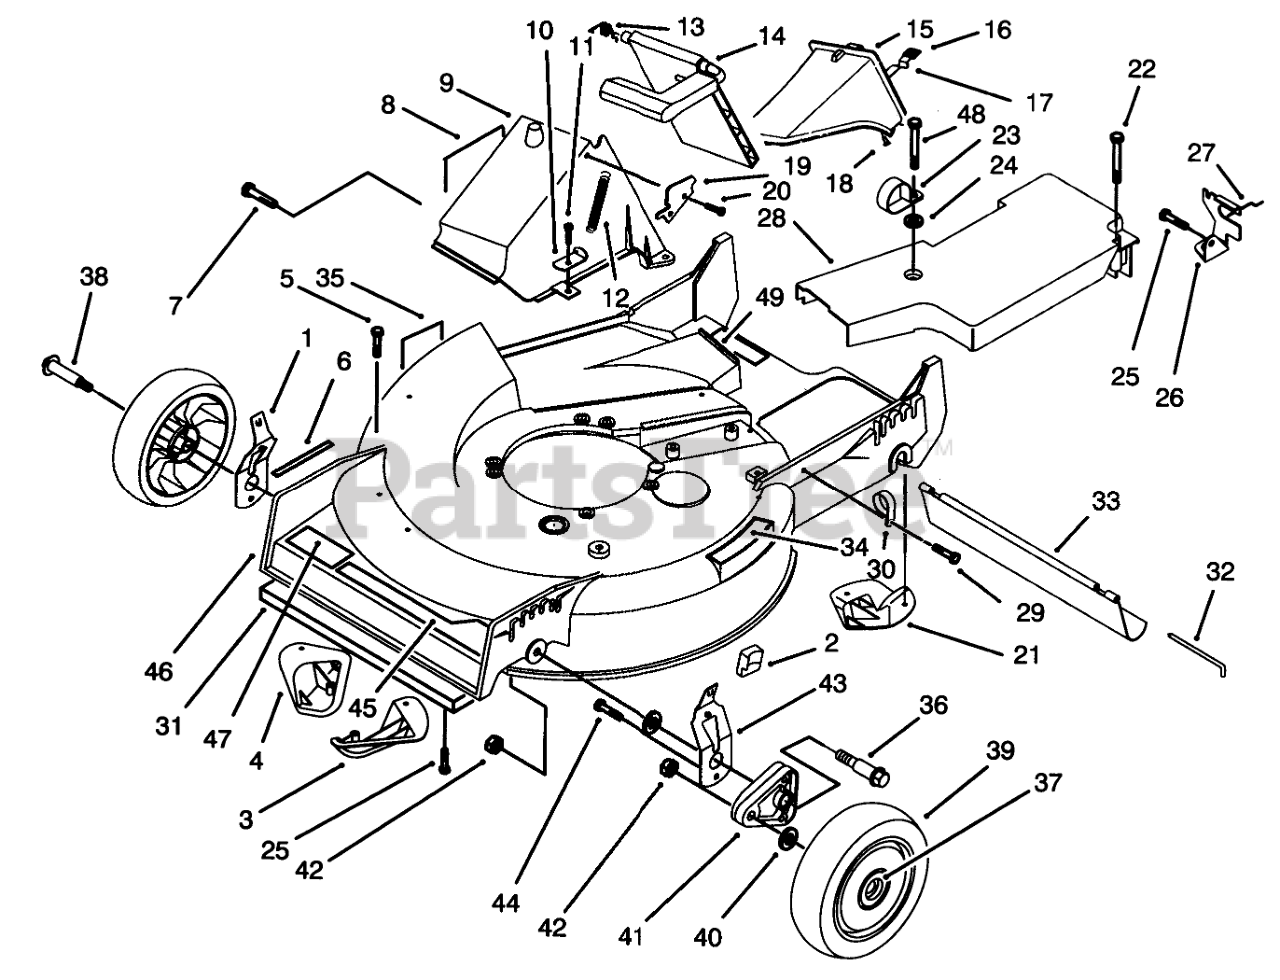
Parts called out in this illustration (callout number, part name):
1	RH SPRING ARM ASSEMBLY
2	KNOB-ARM
3	KICKER-FRONT
4	KICKER-RH
5	SCREW-PPH
6	DECAL - HOC
7	SCREW AND WASHER ASM
8	DECAL - DANGER
9	Tunnel-Discharge (Incl. Ref. #8)
10	BRACKET-SPRING
11	SCREW-HWH
12	SPRING-DOOR
13	RETAINER-DOOR
14	DOOR ASSEMBLY
15	Discharge Plug Assembly (Incl. Ref. #16-18)
16	GRIP-LATCH
17	LATCH-PLUG, DISCHARGE
18	RIVET-HEAD, FLAT
19	DOOR LATCH PLATE
20	SCREW-PLASTITE
21	KICKER-REAR
22	SCREW-HHFTF
23	CLAMP-CABLE
24	WASHER
25	SCREW-HWHTF
26	Bracket-Adj. Trac
27	RETAINER-CABLE
28	BELT COVER
29	SCREW-HWH
30	CLAMP-CABLE
31	Shield-front
32	ROD-SHIELD
33	SHIELD-TRAILING
34	DECAL - STEP PAD INT'L
35	Decal Danger
36	SCREW-SHOULDER
37	BUSHING
38	BOLT-WHEEL
39	Wheel & Tire Assembly (Incl Ref. #37)
40	WASHER
41	ARM-PIVOT, FRONT
42	NUT-LOCK
43	LH SPRING ARM ASSEMBLY
44	SCREW-HWH
45	DECAL - DECK
46	Housing Assembly (Incl. Ref. #3-6, & 21 pg.1) (Incl. Ref. #5 & 6 pg. 3)
47	DECAL
48	SCREW-SPECIAL
49	DECAL FRENCH REGUL.
